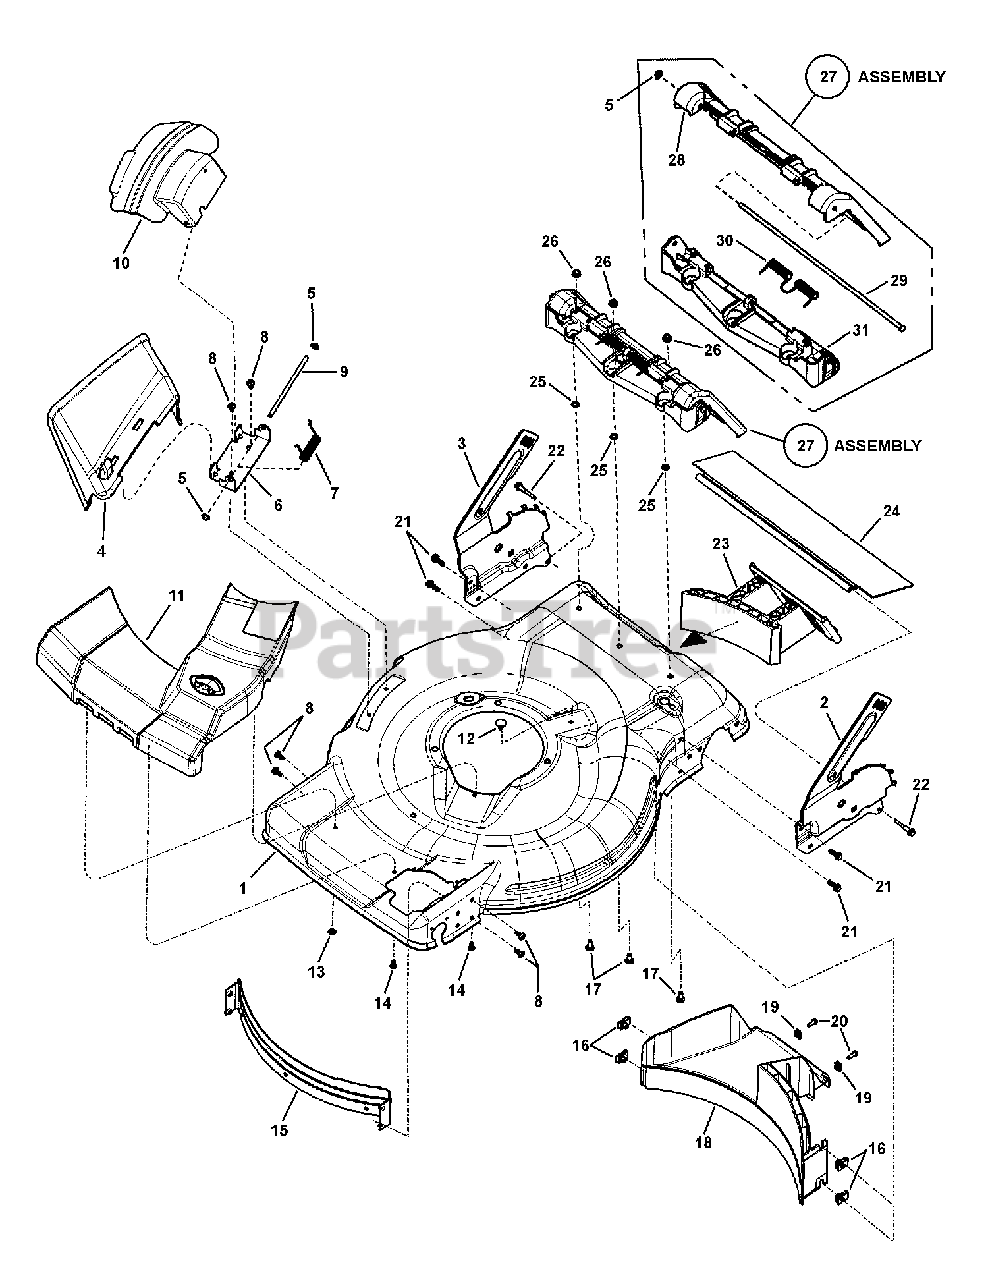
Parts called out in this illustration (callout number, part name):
1	DECK, 22" Front Wheel Drive, Washout
2	BRACKET, Lower Handle, HW, LH
3	BRACKET, Lower Handle, HW, RH
4	CHUTE, Side Discharge, 22" WBM
5	PUSHNUT, 1/4"
6	BRACKET, Chute
7	SPRING, Torsion, Chute
8	SCREW, 1/4-20 x .550 Pan Head Torx (T-30)
9	ROD, Pivot
10	COVER, Mulching
11	ASSEMBLY, Belt Cover w/Heat Patch, Snapper
12	PLUG, Panel, .25 x .61L, Black
13	NUT, 3/16" Push
14	SCREW, 4.8 x 1.59 x 13mm, Round Washer Head Hi-Lo (Torx)
15	BAFFLE, Front
16	U-NUT, 1/4-20
17	BOLT, 1/4-20 x 5/8" Flat Head Square Neck, GR 5
18	BAFFLE, Rear, Front Wheel Drive, WBM
19	SPEED NUT, #10-24 Retainer w/Extrusion
20	SCREW, #10-24 x 5/8" Hex Washer Face Self-Tap, GR 5
21	BOLT, 1/4-20 x 3/4" Hex Flange Lock, GR 5
22	BOLT, Drag Shield, 1/4-20 x 1-1/2"
23	PLUG, Mulching, 22" Deck
24	GUARD, Rear 22"
25	RETAINER, 1/4" Bolt
26	NUT, 1/4-20 Hex Flange Lock
27	DOOR ASSEMBLY, 22" Walk-Behind-Mower
28	DOOR, Rear Discharge
29	ROD, Pivot, Rear Door
30	SPRING, Rear Door (Torsion)
31	DOOR HINGE, Rear Discharge
